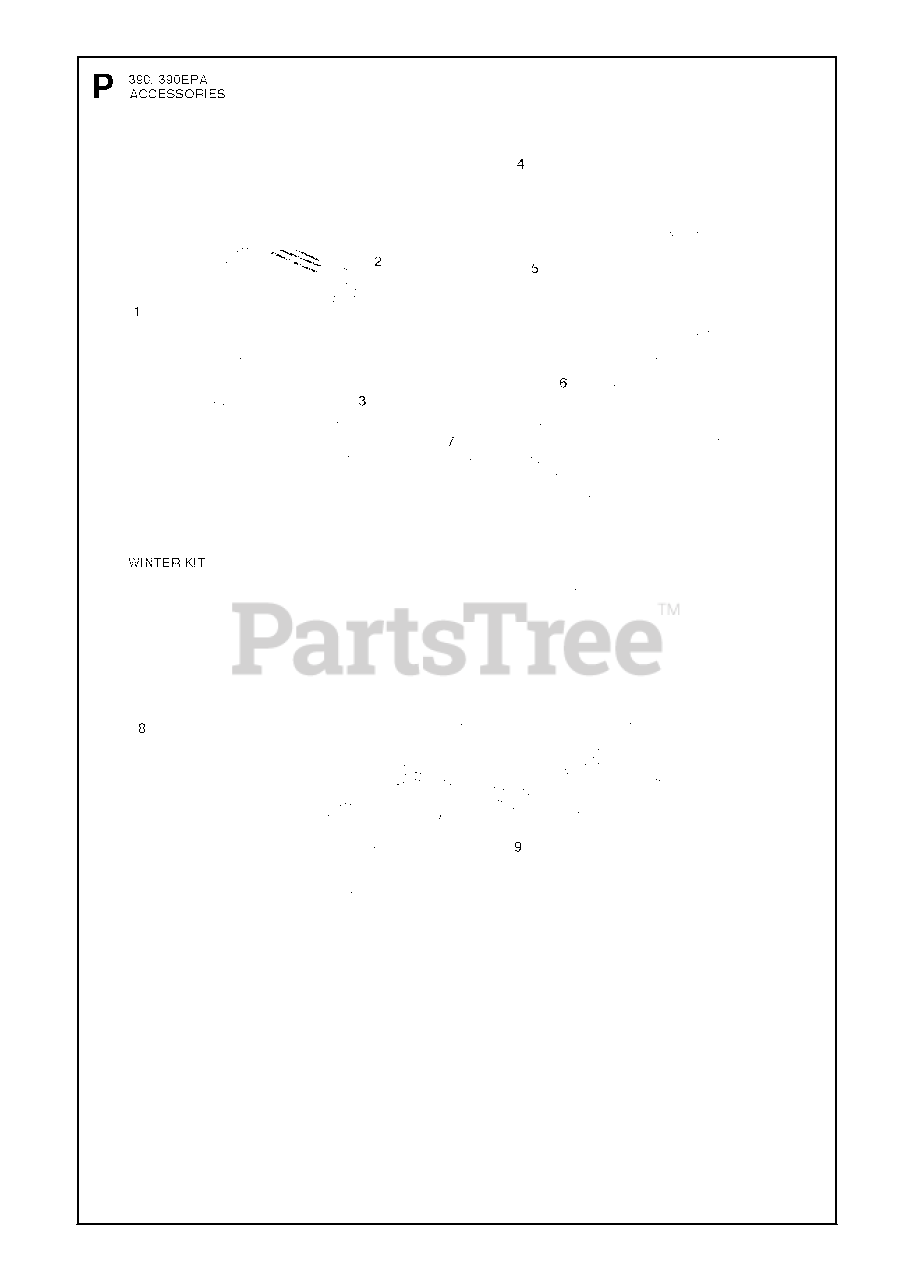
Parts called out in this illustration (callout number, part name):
2	GREASE
3	Grease Gun
4	COMBI TOOL
5	L-SPANNER
6	L-SPANNER
7	COMB.TOOL 8-10-14
8	WINTER SET
9	SCREW
